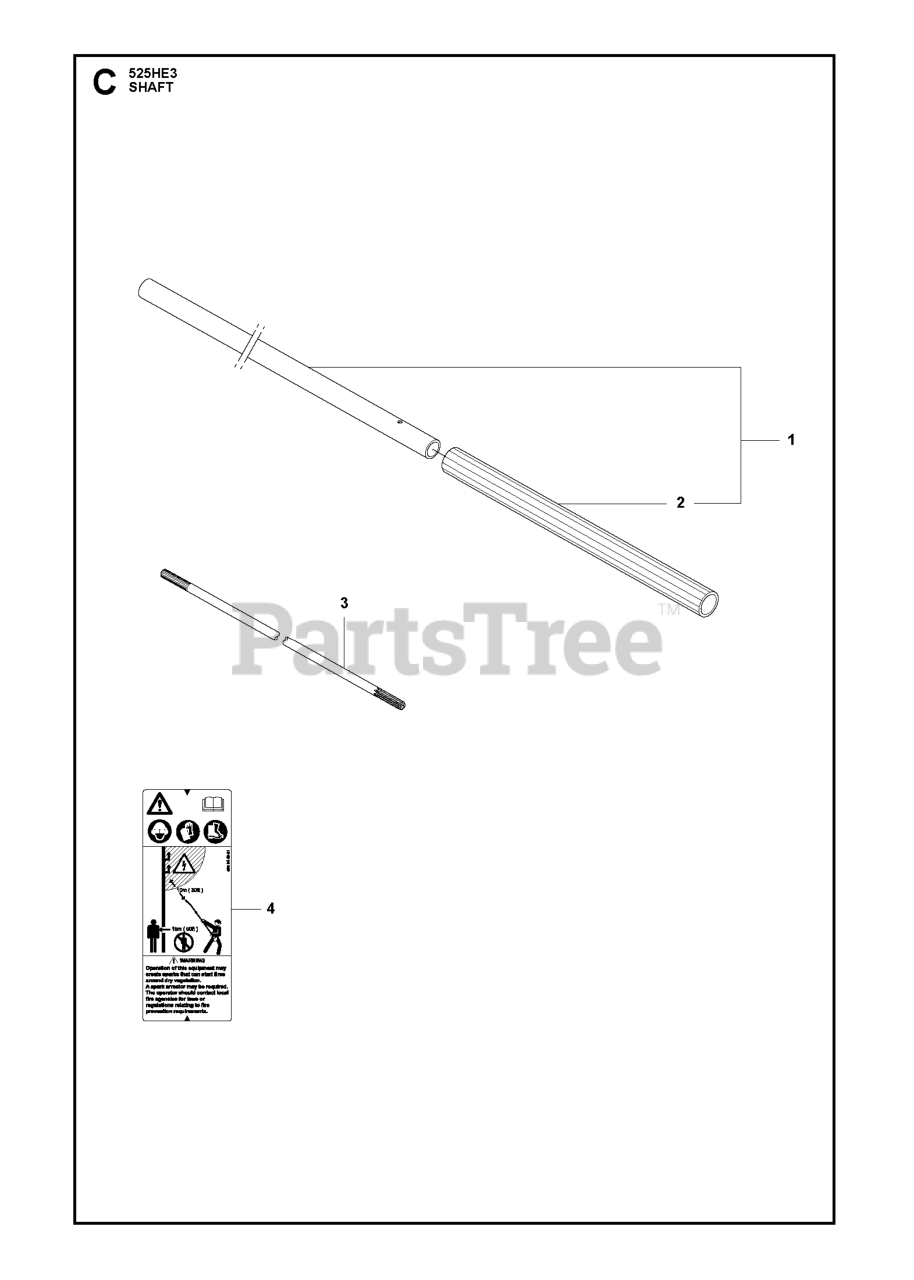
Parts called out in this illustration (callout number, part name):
1	TUBES
3	DRIVE SHAFT
4	DECAL WARNING SPARK ARRESTOR
